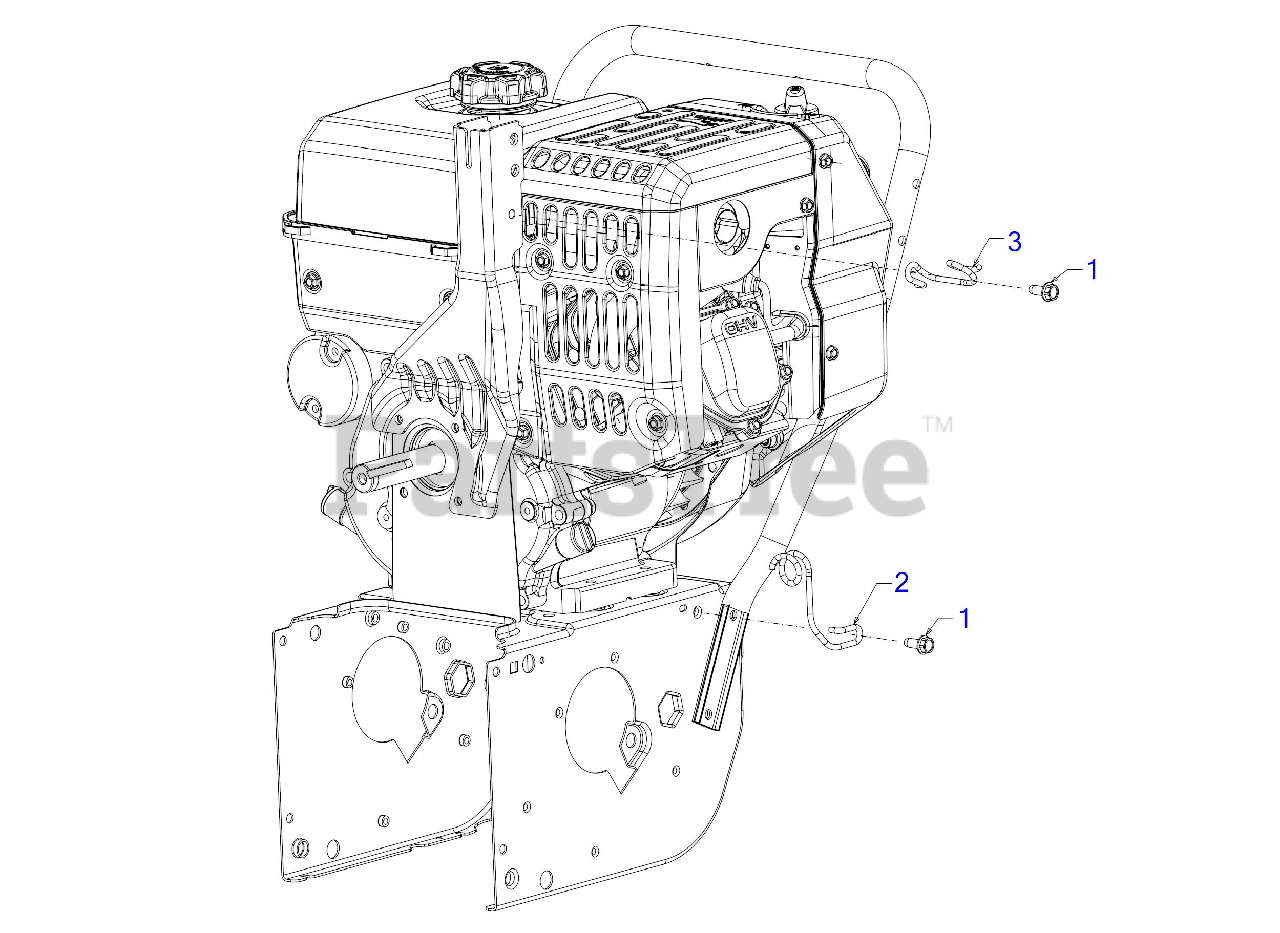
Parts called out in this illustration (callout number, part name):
1	SCREW 5/16-18 x .750
2	GUIDE-CABLE FRAME
3	GUIDE-CABLE
